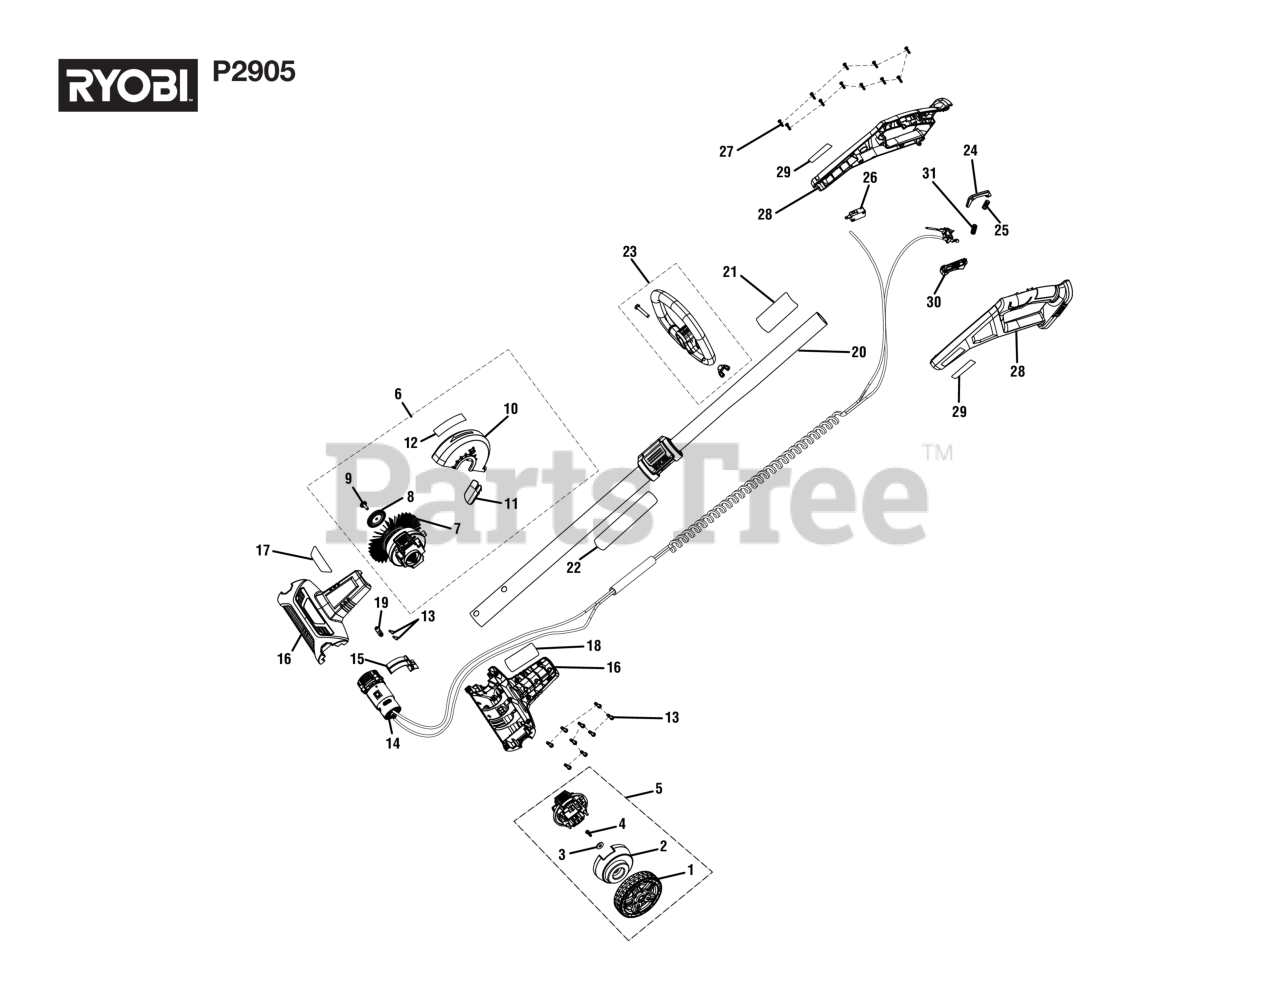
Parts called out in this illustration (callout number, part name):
3	Washer (OD14 x ID5.1 x 1.4t)
4	Screw (M4 x 18 mm, T20 Torx Pan Hd. S.T.)
5	Wheel Assembly (Inc. Key Nos. 1-4)
6	Wire Brush Assembly (Inc. Key Nos. 7-12)
7	Wire Brush
8	Lock Plate (Left)
9	Screw (M5 x 13 mm, Hex Recess Hd.)
10	Guard (Inc. Key No. 12)
11	Splash Guard
12	Icon Label
13	Screw (M4 x 16 mm, Pan Hd.)
14	Motor and Gear Assembly
15	Air Channel
16	Motor Housing Assembly (Inc. Key Nos. 17-18)
17	Logo Label
18	Data Label
19	Wire Press Plate
20	Telescope Shaft Assembly (Inc. Key Nos. 21-27)
21	Icon/Warning Label
22	Shaft Warning Label (FR/SP)
23	Auxiliary Handle Assembly
24	Lock-Out Button
25	Compression Spring
26	Micro Switch
27	Screw (M3.5 x 14 mm, Pan Hd.)
28	Rear Handle Assembly (Inc. Key No. 29)
29	Logo Label
30	Switch Trigger
31	Compression Spring
